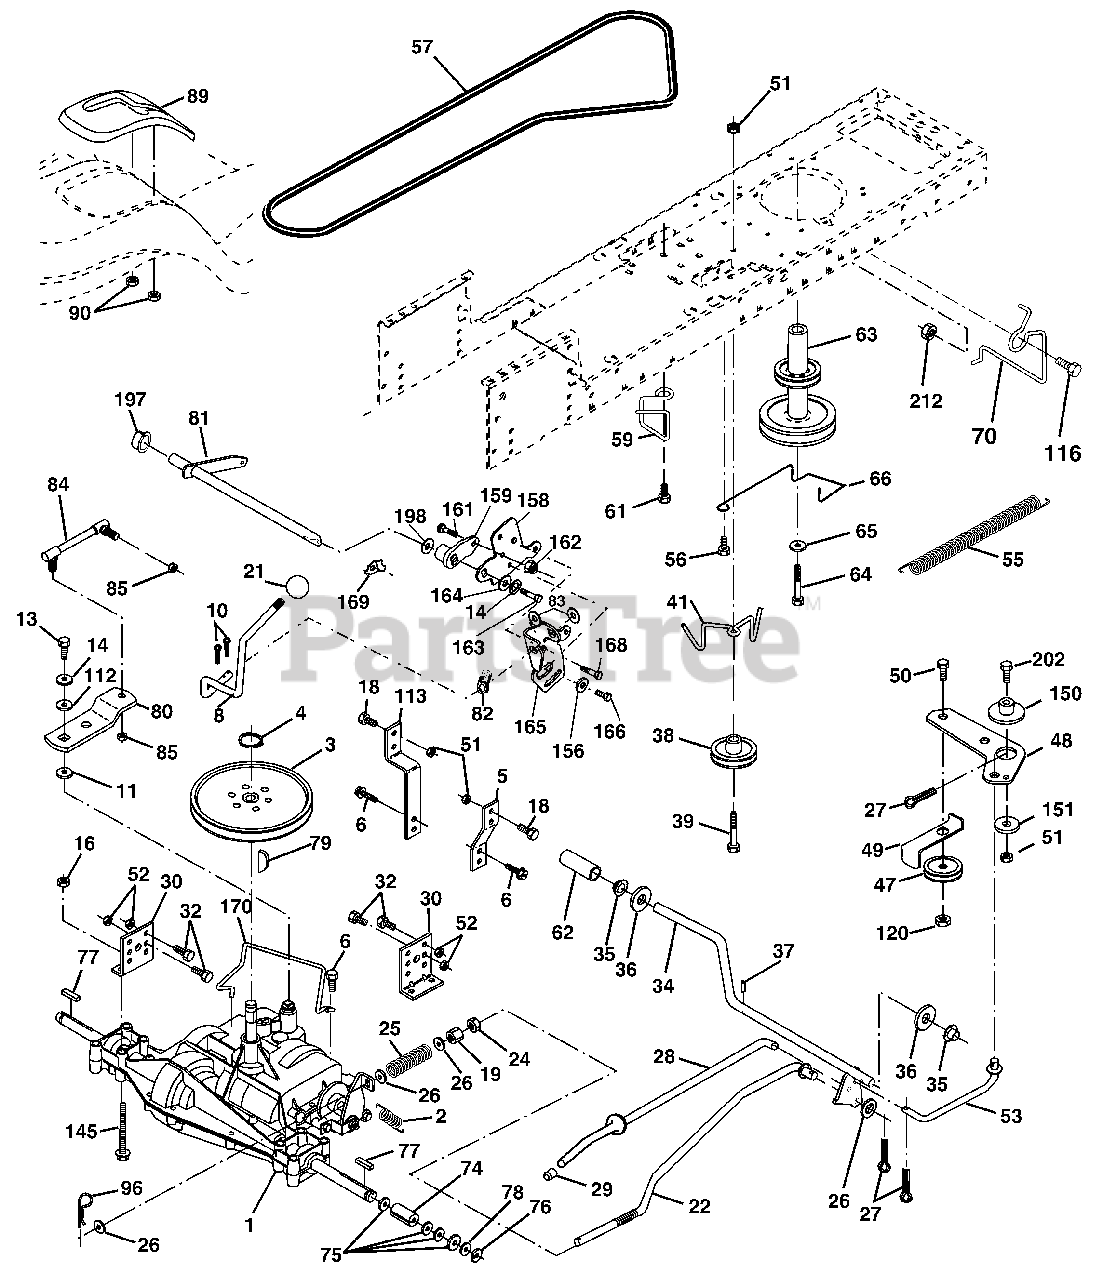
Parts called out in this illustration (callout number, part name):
2	Spring Return Brake T/a Zinc
3	Pulley Transaxle 18" tires
4	Ring Retainer # 5100-62
5	Strap Torque 30 Degrees
6	Screw Thdrol 5/16-18
8	Rod Shift Fender Adjust Lt
10	Pin Cotter 1/8 X 1 Cad
11	Washer Plate Shf 388 Sq Hole
13	Bolt 1/4-28 Unf Gr 8 W/Patch
14	Washer Lock Hvy Helical
16	Nut Lock Hex w/Ins 5/16-18
18	Bolt, Fin Hex 3/8-16 UNC x 1 Gr. 5
19	Nut Lock 3/8-16 Unc
22	Rod Brake Blk Zinc 26 840
24	Nut Hex Jam 3/8-16 Unc
25	Spring Rod Brake 2 00 Zinc
26	Washer 13/32 X 13/16 X 16 Ga
27	Pin Cotter 1/8 X 3/4 Cad
28	Rod Brake Parking LT/YT
29	Cap Brake Parking Black
30	Bracket Mtg Transaxle
32	Bolt Hex Hd 5/16-18unc X 3/4
34	Shaft Asm Pedal Foot
35	Bearing Nylon Blk 629 Id
36	Washer 21/32 X 1 X 16 Ga
37	Pin Roll 3/16 X 1"
38	Pulley Idler Composite
39	Bolt Fin Hex 3/8-16 Unc x 3
41	Keeper Belt Idler Flat
47	Pulley Idler V Groove Plastic
48	Bellcrank Clutch Grnd Driv
49	Retainer Belt Style Spring
50	Bolt Carr. 3/8-16 x 1-1/2 Gr. 5
51	Nut Crownlock 3/8-16 Unc
52	Nut Crownlock 5/16-18 Unc
53	Link Clutch
55	Spring Return Clutch 6 75
56	Screw 3/8-16 x 1 1/4
57	V-Belt Ground Drive 95 25
59	Keeper Belt Span Ctr
61	Screw 3/8-16 x .875
62	Cover Pedal Round
63	Engine Pulley LT/YT
64	Bolt Hex
65	Washer Lock Hvy Hlcl Spr 7/16
66	Keeper Belt Engine Foolproof
70	Guide Belt Mower Drive RH
74	Spacer Axle
75	Washer 25/32 X 1 1/4 X 16 Ga
76	E-ring #5133-75
77	Key Square 2 0 X 1845/ 1865
78	Washer 25/32 X 1-5/8 X 16 Ga
79	Key Woodruff #9 3/16 x 3/4
81	Shaft Asm Cross
82	Spring Torsion T/a
83	Washer 17/32 X 3/4 X 16 Ga
84	Link Transaxle
85	Nut Lock Center 1/4 - 28 FNTHD
89	Console Shift STLT
90	Nut Self-thd Wsh-hd 1/4 Zinc
96	Retainer Spring 1"
112	Washer 9/32 x 3/4 x 10 Ga.
113	Strap Torque LT
116	Bolt Rdhd Sq Neck 3/8-16 x 1.0
120	Nut Lock Flg. 3/8-16 Unc
145	Bolt Hex 5/16-18 Gr. 5
151	Washer 13/32 x 2 x 10 Ga.
156	Washer Srrted 5/16ID x 1.125
158	Bracket Shift Mount
159	Hub Tapered Flange Shift Lt
161	Bolt Rdhd Sqnk 1/4-20 x 3/4 Gr 5
162	Nut Crownlock 1/4-20 Unc
163	Bolt Hex Fin 1/4-20 Unc x 1 Gr 5
164	Washer 5/8 x .281 x 10 Ga
165	Bracket Pivot Lever
166	Screw 5/16-18 x 5/8
168	Bolt Shoulder 5/16-18 x .561
169	Plate Fastening Lt
170	Keeper, Belt T/A D/P
197	Nyliner Snap-In
198	Washer Nyl 7/8 ID x 105"
202	Bolt RDHD 3/8-16 x 1-3/4 Gr. 5
212	Nut, Hex Flange Lock
